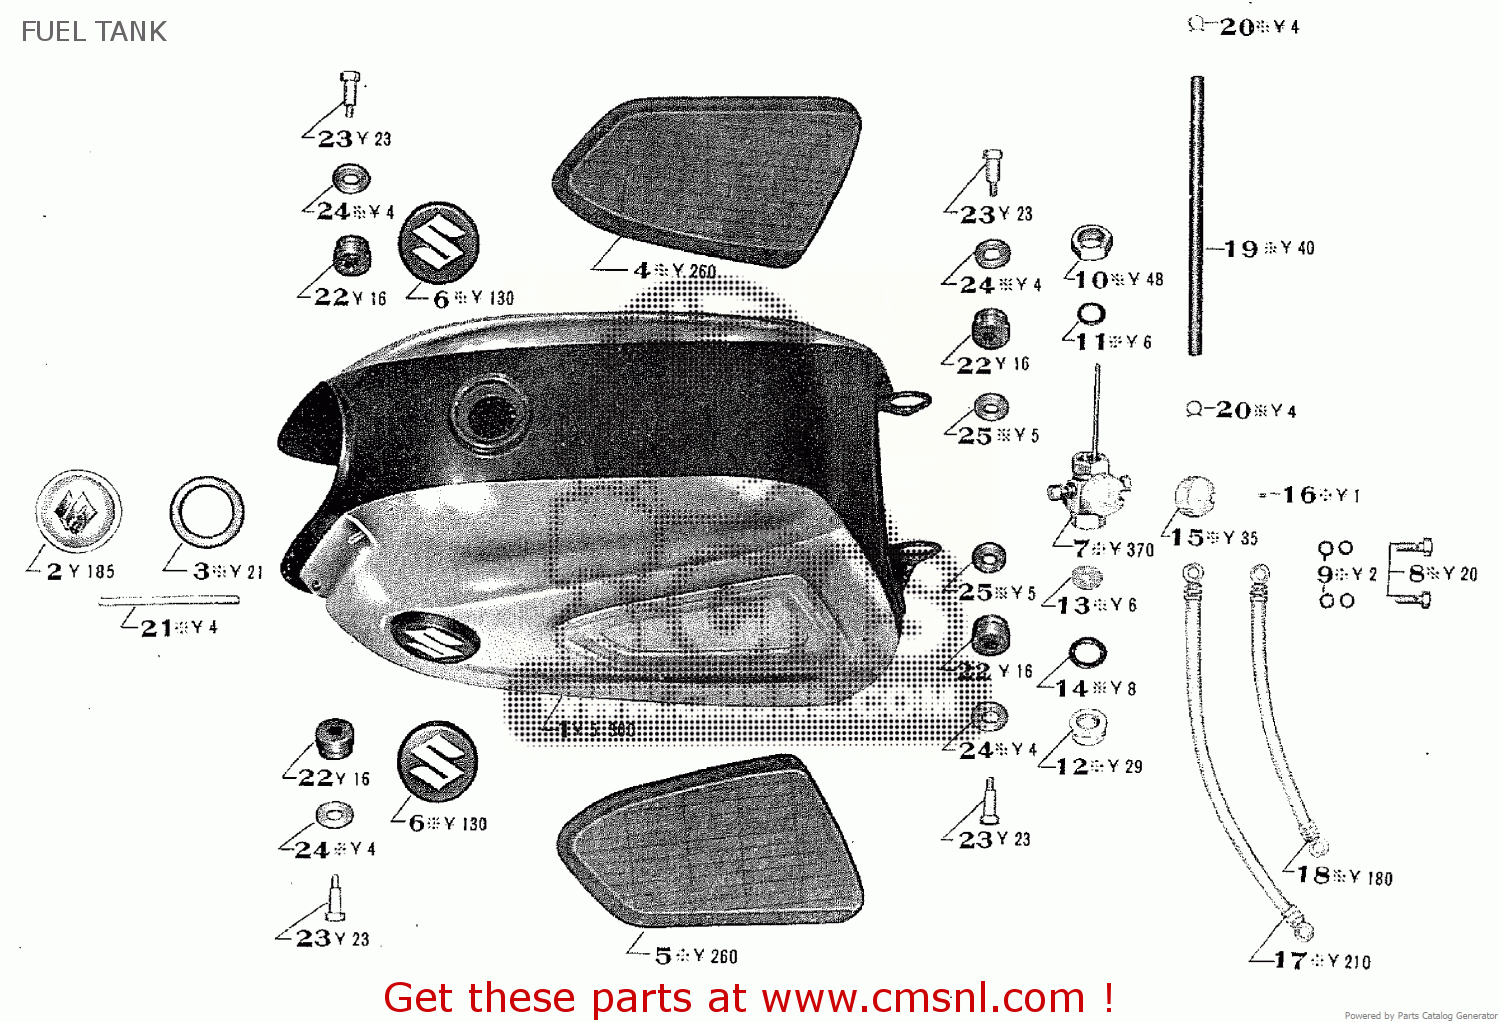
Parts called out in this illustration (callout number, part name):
1	FUEL TANK COMP
2	TANK CAP ASSY.
3	TANK CAP PACKING
4	RIGHT KNEE GRIP
5	LEFT KNEE GRIP
6	TANK MARK
7	FUEL COCK ASSY.
8	BANJO BOLT
9	BANJO PACKING
10	FILTER JOINT NUT
11	FILTER JOINT PACKING
12	STRAINER CUP
13	STRAINER NET
14	STRAINER CUP PACKING
15	FILTER DIAL COMP.
16	DIAL SET SCREW
17	RIGHT FUEL PIPE COMP.
18	LEFT FUEL PIPE COMP.
19	TANK CONNECTING PIPE
20	CONNECTING PIPE SET CLIP
21	FUEL GAUGE PIPE
22	TANK SET RUBBER
23	TANK SET BOLT
24	WASHER
25	TANK SET WASHER
